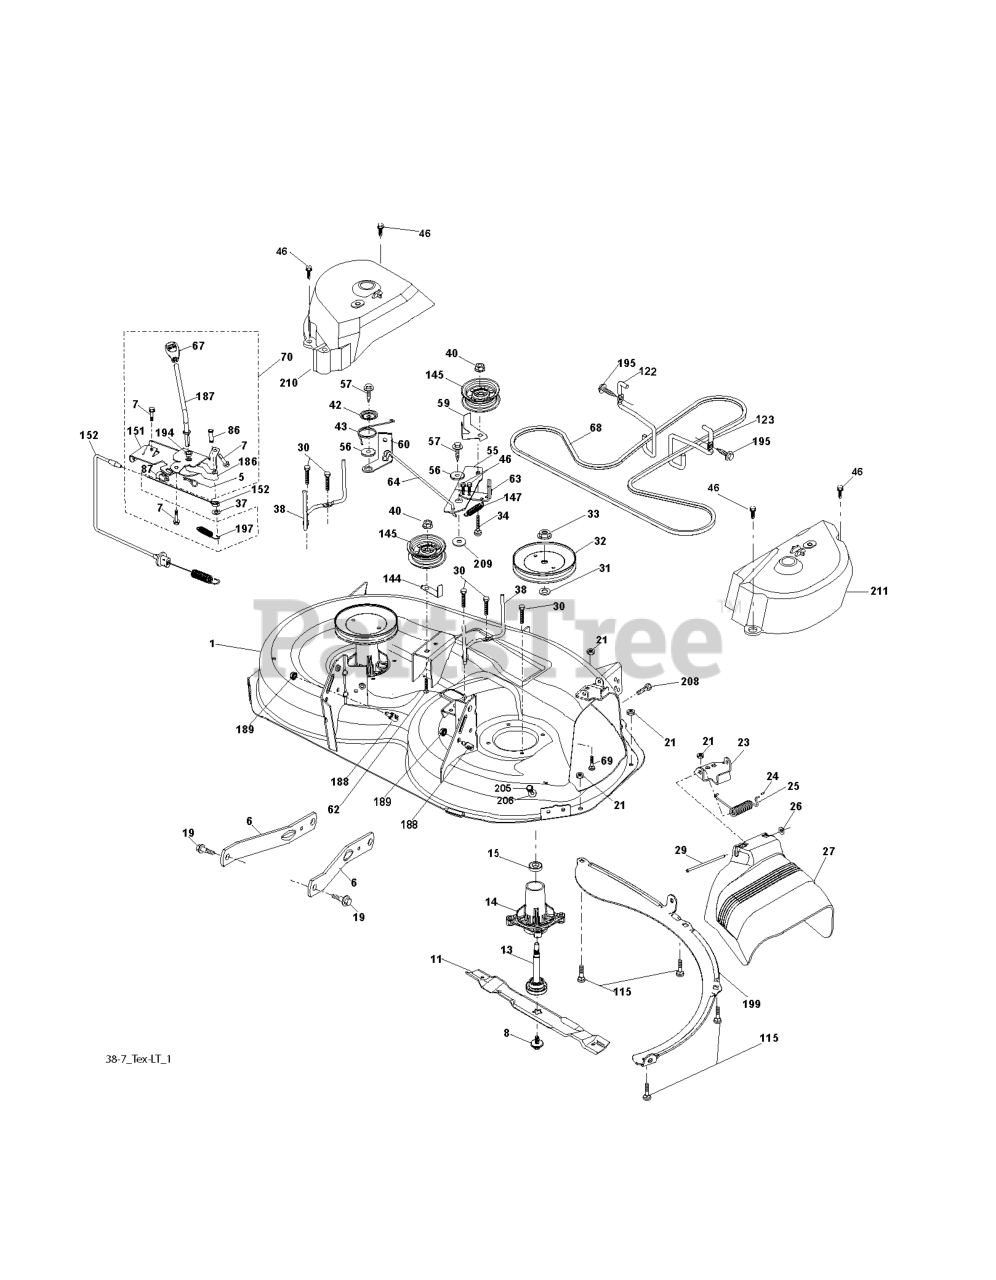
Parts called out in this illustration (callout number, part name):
1	HOUSING
5	RETAINER-SPRNG RB
6	ARM.SUSPENSION.MOWER.R
7	SCREW
8	BOLT.WASHER.ASM.7/16-2
11	BLADE 38" PREMIUM
13	SHAFT.ASM.MDRL.N/GREASE.38
14	RP.HOUSING.MANDREL.4PT.
19	BOLT.SHOULDER
21	LOCKNUT
23	BRKT.DEFLECTOR.38"2005+
24	CAP-SLEEVE LT
25	SPRING.TORSION.DEFLECT
26	NUT PUSH M
27	SHIELD ASM.DFLCTR MWR.38-7"BLK
29	ROD.HINGE
30	SCREW, WASHER HEAD
31	WASHER.SPACER.MANDREL
32	PULLEY.MANDREL.5.0.PD.38"
33	NUT.FLANGE.LOCK.TOP
34	BOLT.3/8-16X1.50
37	WASHER
38	KEEPER BELT LH MANDREL
40	NUT LOCK FLG 3/8-16 UNC
42	SPRING.TORSION.BRAKE
43	SRPING.TORSION.RETAINE
46	SCREW.1/4-20X5/8
56	SPACER.RETAINER
57	SCREW 3/8-16X1
59	GUARD, BELT
60	ARM BRAKE MOWER RH 38"
62	BOLT.3/8-16X1.50
63	RP ARM.BRAKE.MOWER.38"LH.TEX
64	LINK BRAKE
67	HANDLE.CLUTCH.CABLE.LT
69	BOLT
70	CLUTCH.ASM.MANUAL.LT.PRED
86	PIN ATTACHMENT CABLE
87	SWITCH.INTRLCK.CLUTCH.
115	BOLT.CARR.5/16-18X5/8.SHORT
122	KEEPER BELT ENGINE LH
123	KEEPER BELT RH
144	KEEPER, BELT IDLER
145	PULLEY.IDLER.48"PRIMARY
147	SPRING RETURN
151	BRACKET.CLUTCH CBL.PRED LT
152	CLUTCH CABLE
186	ARM ACTUATOR
187	LEVER.CONTROL.CL.CABLE.PRED LT
188	STUD.FASTNER.W/ANTI-ROTATE
189	NUT LOCK HEX FLANGE 5/16-18
194	BEARING.CONTROL.LEVER.CLUTCH
195	SCREW, 3/8-16X3/4
197	SPRING.PLUNGER.ACTUATOR
199	BAFFLE.VORTEX.FRONT.38"
205	SCREW
208	SCREW 3/8-16X1/2
209	WASHER 12/32X2X10GA
